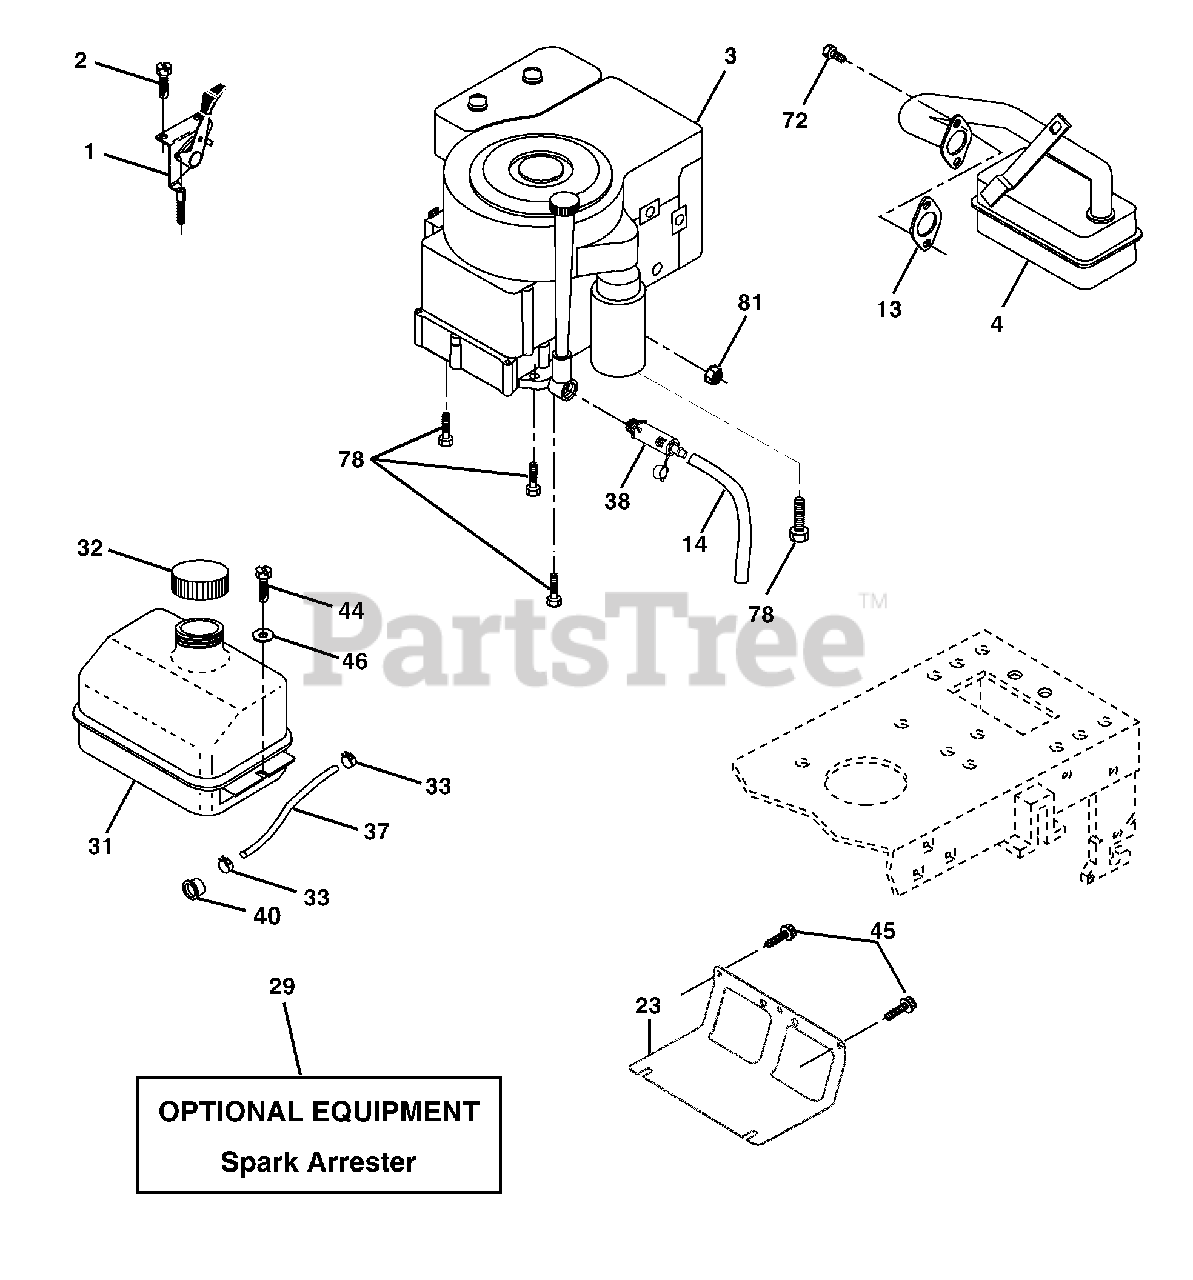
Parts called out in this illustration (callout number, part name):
1	Control Throttle/Choke Flag
2	Screw Hex Thd Cut 1/4-20 x 1/2
4	Muffler Exhaust B&S
13	Gasket Eng 1 313 Id Tin Plated
14	Tube Drain Oil Easy
23	Shield BRN/DBR Guard
29	Kit Spark Arrestor (Flat Scrn)
31	Tank Fuel Front
32	Cap Asm Fuel
33	Clamp Hose
37	Line Fuel 20"
38	Plug Drain Oil
40	Bushing Snap Nyl Blk Fuel Line
44	Screw Thdrol 1/4-20 x 3/4
45	Screw Hex Wsh Thdrol 3/8-16
46	Washer 9/32 X 7/8 X 16 Ga.
72	Screw Socket Head 5/16-18 x 1
78	Screw 3/8-16 x 1-1/4
81	Nut Keps Hex 1/4-20 unc
